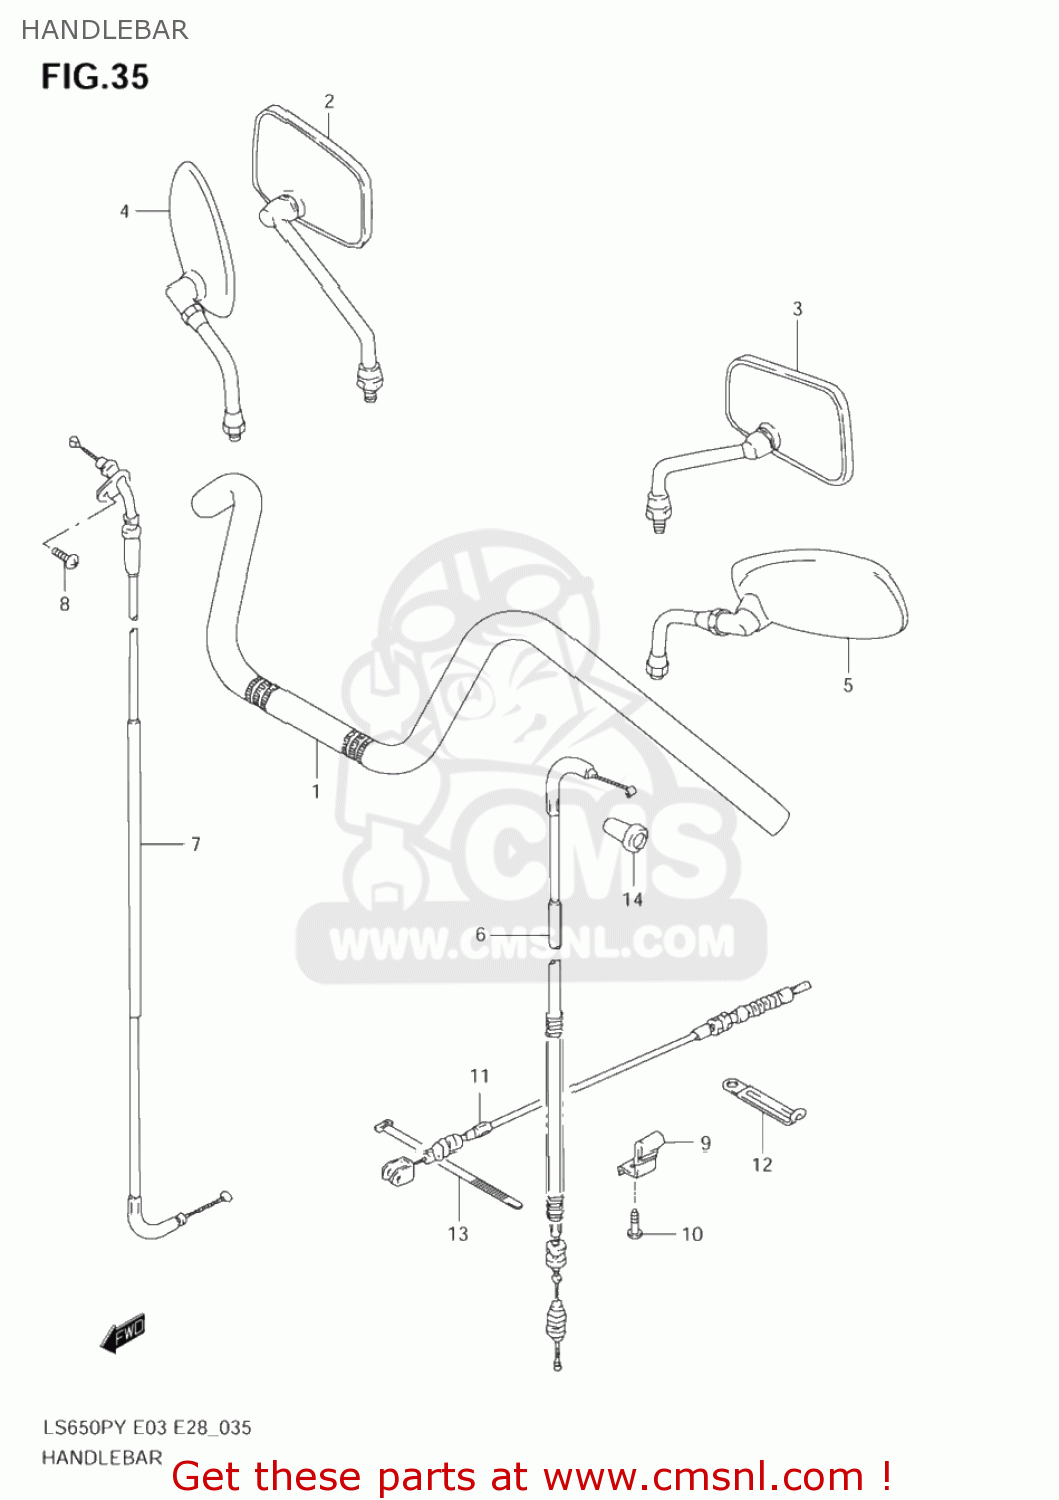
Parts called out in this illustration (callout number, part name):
1	HANDLEBAR
2	MIRROR ASSEMBLY,REAR VIEW
3	MIRROR ASSY,RR VIEW,L
4	MIRROR ASSY,RE
5	MIRROR ASSY,RE
6	CABLE ASSY,CLUTCH
7	CABLE ASSY,THROTTLE
8	SCREW
9	CLAMP,STOP LAMP SWITCH CABLE
10	BOLT
11	CABLE,STOP LAMP SWITCH
12	CLAMP(L:65)
13	CLAMP(L:145)
14	BOOT,CLUTCH CABLE
